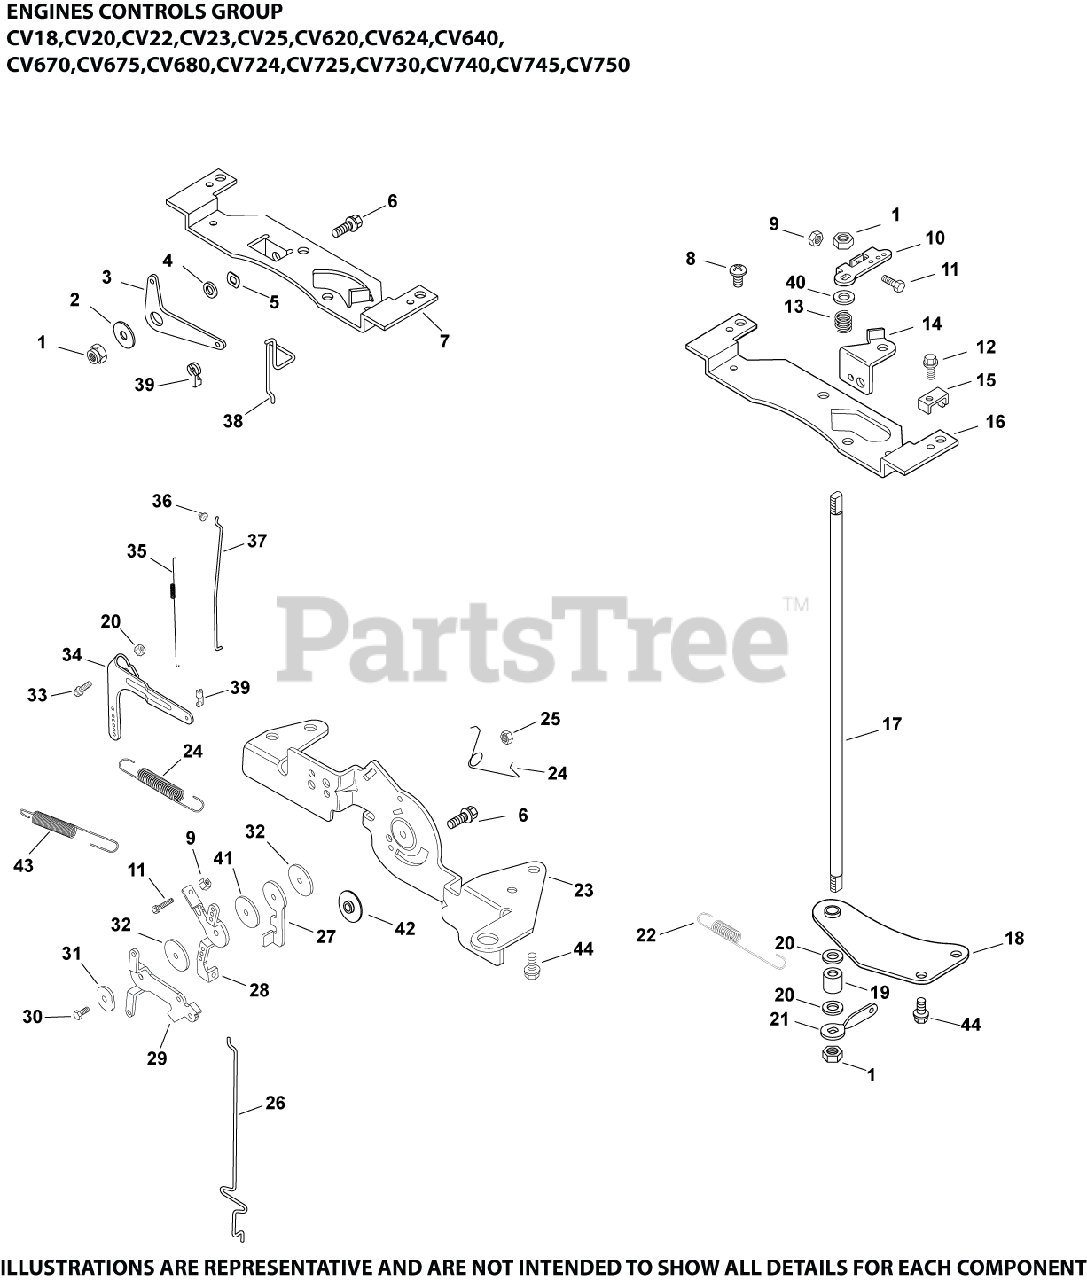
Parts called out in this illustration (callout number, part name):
9	NUT, M4X0.7
11	SCREW, SLT HD CAP M4X0.7X25
12	SCREW,FLG THD FRM M5X0.8X16-(#25086398S)
12	SCREW, LBD THD FRM M5x0.8x16 - USE 25 086 405-S
15	CLAMP, DUAL CONDUIT
20	NUT, FLG M6X1.0
22	SPRING, GOVERNOR (ORANGE)
23	BRACKET, CONTROL-USE 24 126 172-S
24	SPRING, CHOKE RETURN
25	NUT, LOCK M5X.8
26	LINKAGE, CHOKE
27	LEVER, THROTTLE ACTUATOR
28	LEVER, THROTTLE CONTROL
29	LEVER, CHOKE
30	SCREW, FLG THD FRM M5X.8X20-(#25086399S)
31	WASHER, SPRING 1/4"
32	WASHER, FLAT 5.5 MM
33	BOLT, RD HD SQ NECK M6X1.0X25
34	LEVER, GOVERNOR-USE 24 090 57-S
35	SPRING, LINKAGE
36	BUSHING, LINKAGE RETAINING
37	LINKAGE, THROTTLE
39	BUSHING, THROTTLE LINKAGE
40	WASHER, FLAT 1/4"
41	WASHER, FLAT 5 MM
42	SPACER, CONTROL ASSEMBLY
43	SPRING, GOVERNED IDLE
44	SCREW,FLG THD FRM M6X1.0X16-(#25086397S)
